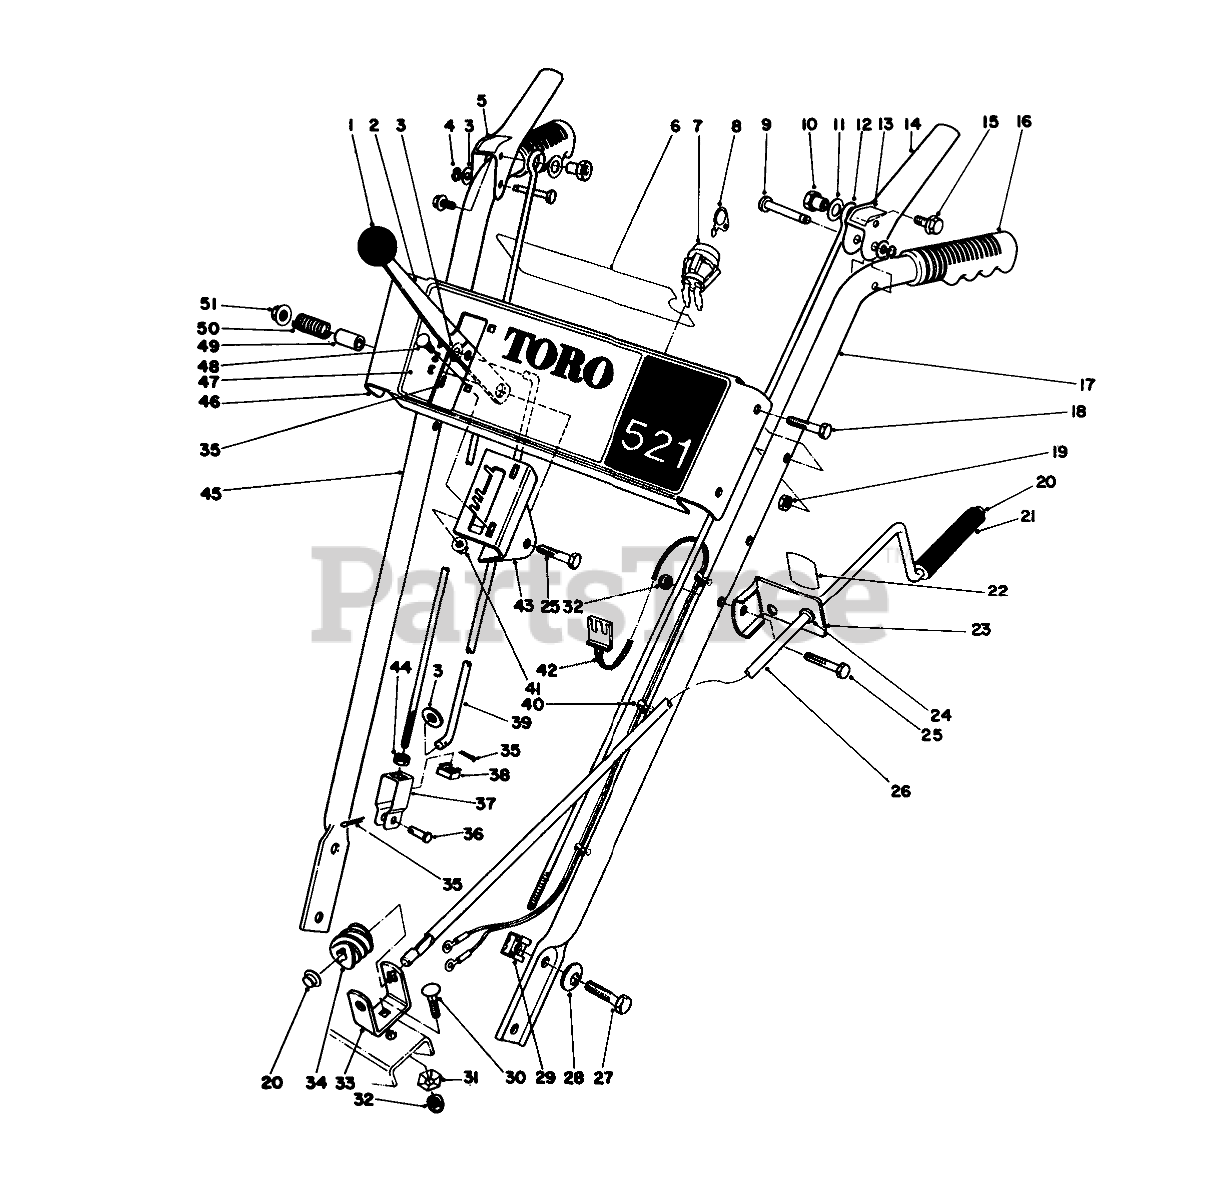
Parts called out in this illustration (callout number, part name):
2	SPEED SELECTOR B
3	WASHER-PLAIN
4	RING-CLIP
5	AUGER DRIVE DECAL
6	BACK DECAL
7	SWITCH
8	Key
9	PIN-LEVER, CONTROL
10	POST-MOUNTING, LINKAGE
11	WASHER-FLAT
12	LINK-UPPER
13	DECAL
14	Handle-Control
15	SCREW-HHF
16	Grip
17	LEFT HANDLE
18	SCREW-HH
19	NUT-LOCK, CONE
20	RETAINER-PUSH ON
21	GRIP-CONTROL, CHUTE
22	CHUTE DECAL
23	Bracket-Chute Control (Incl. Ref. #22 & 24)
24	Bushing
25	SCREW-HH
26	ROD-CONTROL, CHUTE
27	SCREW-HH
28	WASHER-BELLEVILLE
30	BOLT-CARR
31	WASHER-LOCK
32	NUT-LOCK, NI
33	BRACKET-WORM
34	GEAR-WORM, CHUTE
35	PIN-COTTER
36	PIN-CLEVIS
37	CLEVIS
38	NUT-RETAINED
39	ROD-SELECTOR, SPEED
40	Mount-Wire
41	NUT-HHF
42	Wire Harness Assembly (Incl. Ref. #40)
43	Mount-Speed Selector
44	NUT-JAM
45	RIGHT HANDLE
46	ESCUTCHEON PLT B
47	CONT PLT DECAL 521
48	SCREW-CARRIAGE
49	SPACER
50	SPRING
51	NUT-HF
